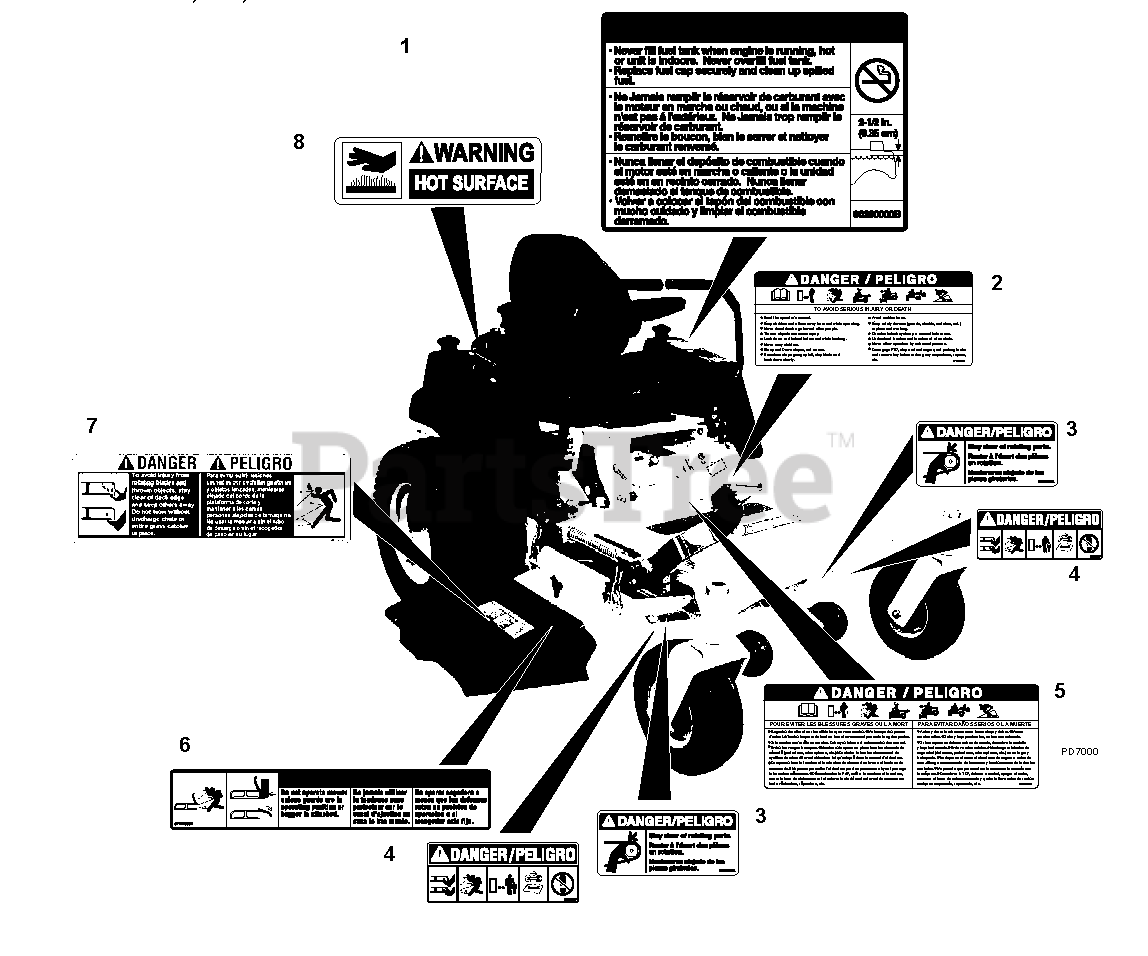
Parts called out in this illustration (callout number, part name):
1	Decal, Fuel Warning
2	Decal, Safety, English
3	Decal, Danger, Rotating Belt
4	Decal, Warning
5	Decal, Safety, French/Spanish
6	Decal, Warning
7	Danger (992411)
8	Decal, Warning, Hot Surfaces
